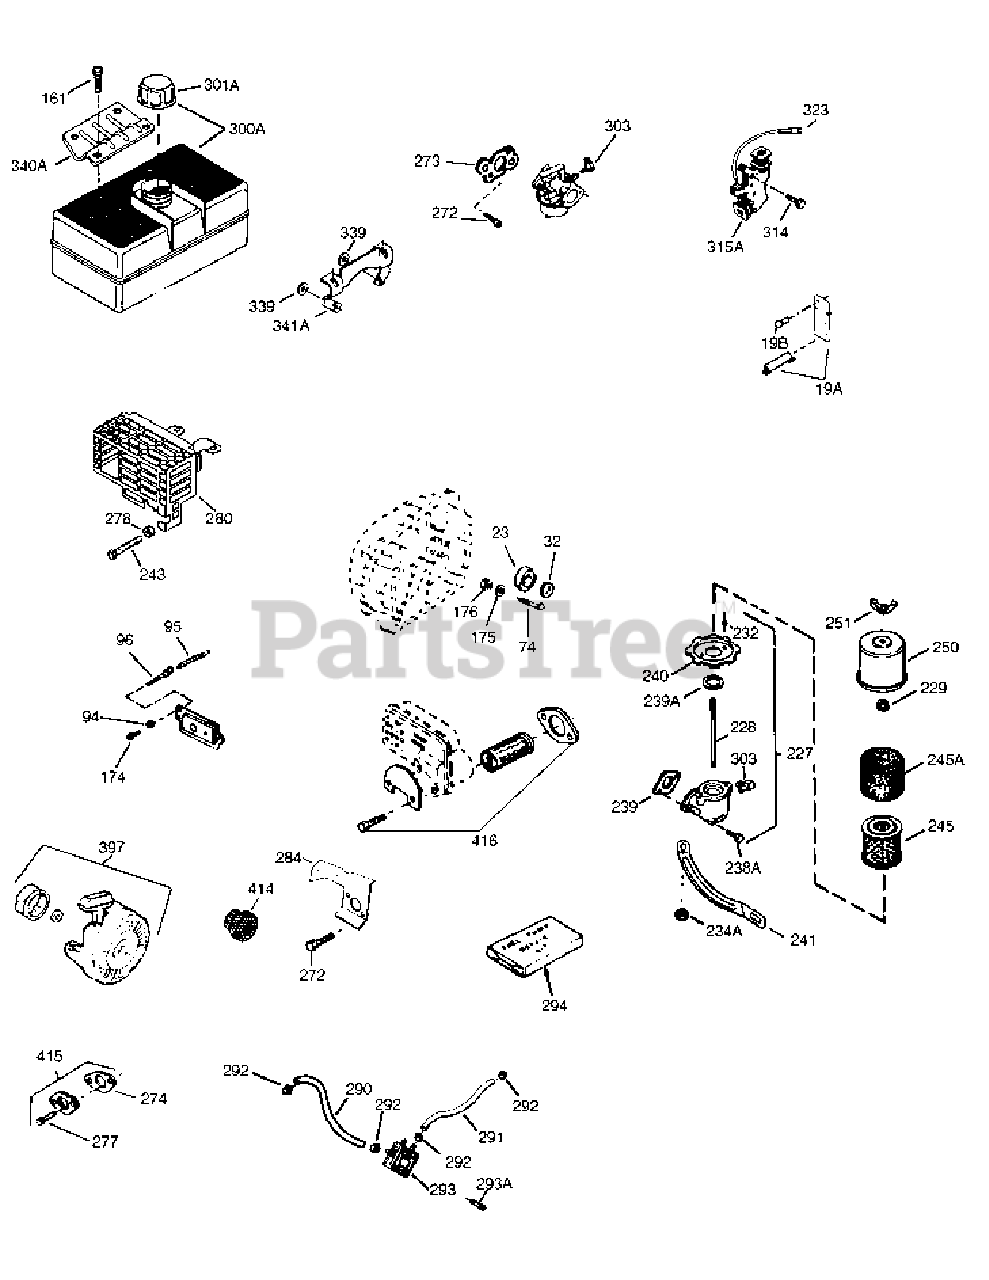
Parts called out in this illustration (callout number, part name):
130	Screw, 5/16-18 x 1-1/2"
130C	Screw, 5/16-18 x 39/64"
174	Screw, 10-24 x 1/2"
182	Screw, 1/4-28 x 1"
222	Screw, 10-32 x 1/2"
264A	Screw, 1/4-20 x 5/8"
277	Screw, 5/16-18 x 4-3/16"
290	Fuel Line 32.0" length
292	Fuel Line Clamp
298	Screw, 1/4-15 x 3/4"
311	Oil Fill Plug Incl. 312)
314	Screw, 1/4-20 x 3/4"
361	Screw, Torx T-30, 1/4-20 x 15/32"
361A	Screw, 6-32 x 2-1/2"
999	Winter Maintenance Kit
